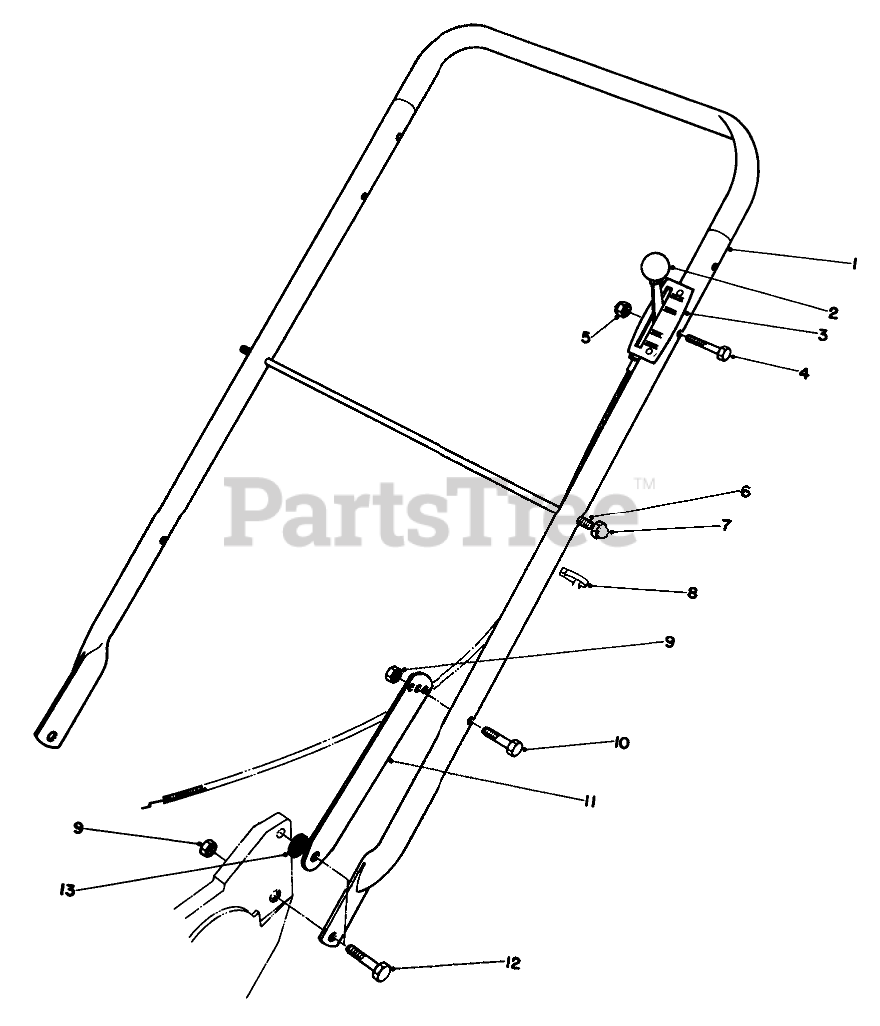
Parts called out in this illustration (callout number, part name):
1	Handle
2	KNOB-CONTROL
3	Control-Throttle (Incl. Ref. #2)
4	SCREW-HH
5	NUT-LOCK, NI
6	ROD-SUPPORT, BAG
7	NUT-CAP
9	NUT-LOCK, CONE
10	SCREW-HH
11	Latch-Handle
12	SCREW-SHOULDER
13	SPACER
